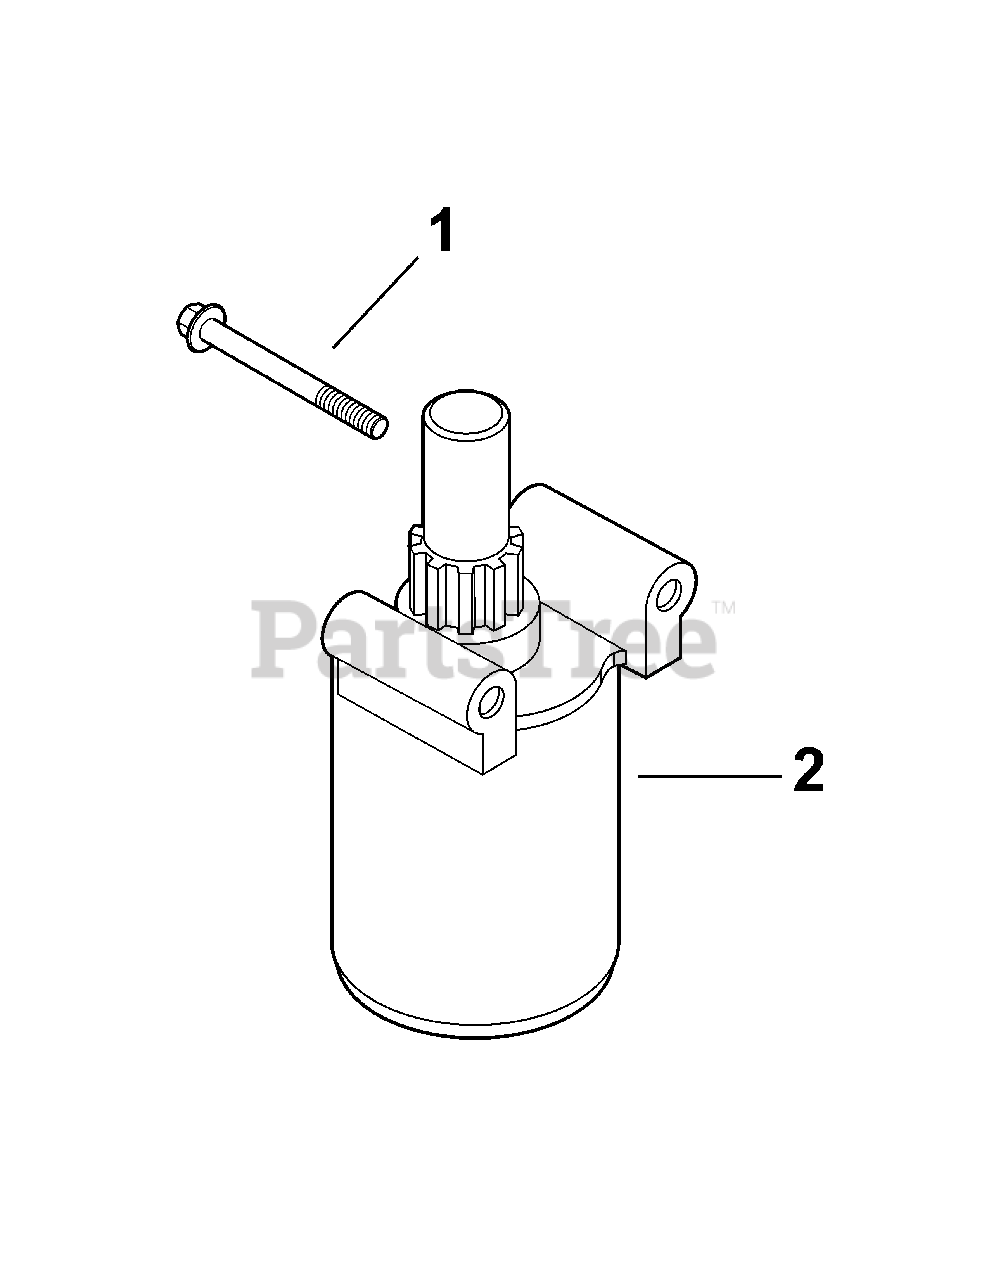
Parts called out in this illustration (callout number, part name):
1	Flg. Screw, M8 X 1.25 X 80
2	Starter Assembly
2	Brush Assembly
2	Kit, Drive with Gear
